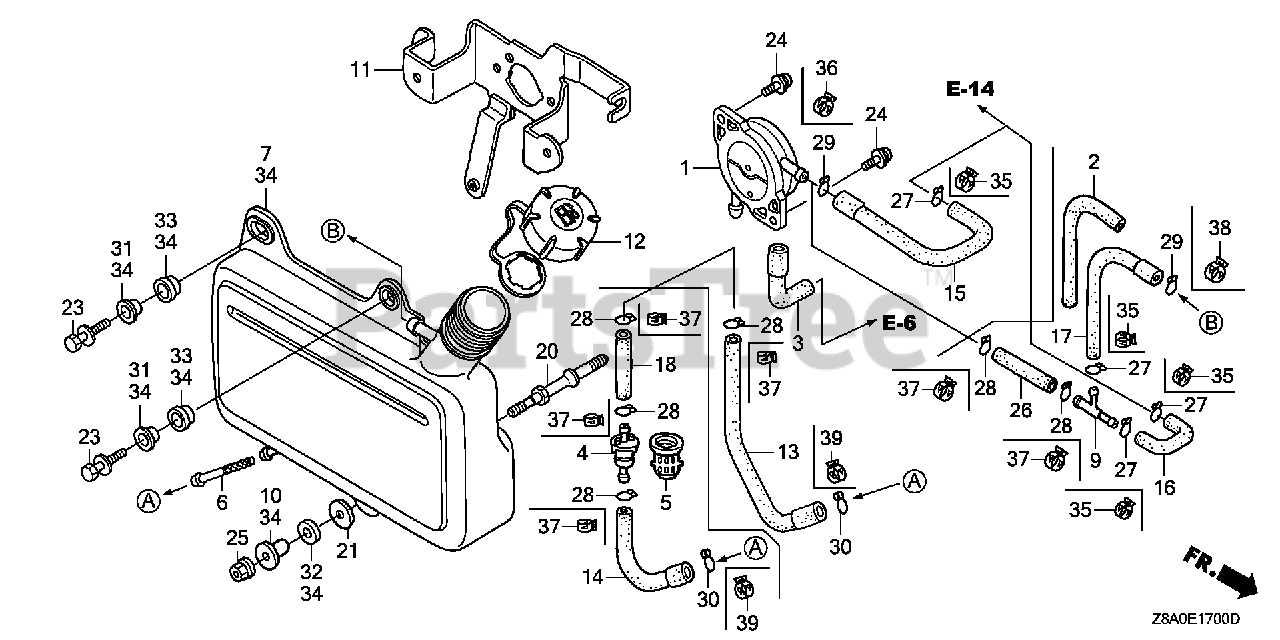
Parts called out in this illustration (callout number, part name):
1	PUMP ASSY., FUEL
2	RUBBER, SUPPORTER (107MM)
3	TUBE, DIAPHRAGM
4	FILTER, FUEL
5	SUSPENSION, STRAINER
7	TANK, FUEL
9	JOINT, FUEL TUBE
10	COLLAR, FUEL TANK SETTING
11	STAY A, FUEL TANK
12	CAP ASSY., FUEL TANK
14	TUBE, FUEL TANK
14	TUBE, FUEL TANK (FKM)
16	TUBE, FUEL
16	TUBE, FUEL (FKM)
17	TUBE, FUEL RETURN
17	TUBE, FUEL RETURN (FKM)
18	TUBE, FUEL PUMP
18	TUBE, FUEL PUMP (FKM)
20	BOLT, FUEL TANK STUD (H=30MM)
21	WASHER (6MM)
23	BOLT-WASHER (6X25)
24	SCREW-WASHER (5X14)
25	NUT, FLANGE (6MM)
26	TUBE, FUEL (5.3X33) (FKM)
26	BULK HOSE, FUEL (5.5X3000) (Honda Code 5338587). (5.5X150)
27	CLIP, TUBE (B8)
28	CLIP, TUBE (B10)
29	CLIP, TUBE (C9)
30	CLIP, TUBE (C11)
31	COLLAR, TANK SET
32	RUBBER A, TANK MOUNTING
33	RUBBER B, TANK MOUNTING
34	TANK KIT, FUEL
35	CLIP, TUBE (D8)
37	CLAMP, TUBE (D10)
38	CLIP, TUBE (10.5MM)
39	CLAMP, TUBE (D12)
